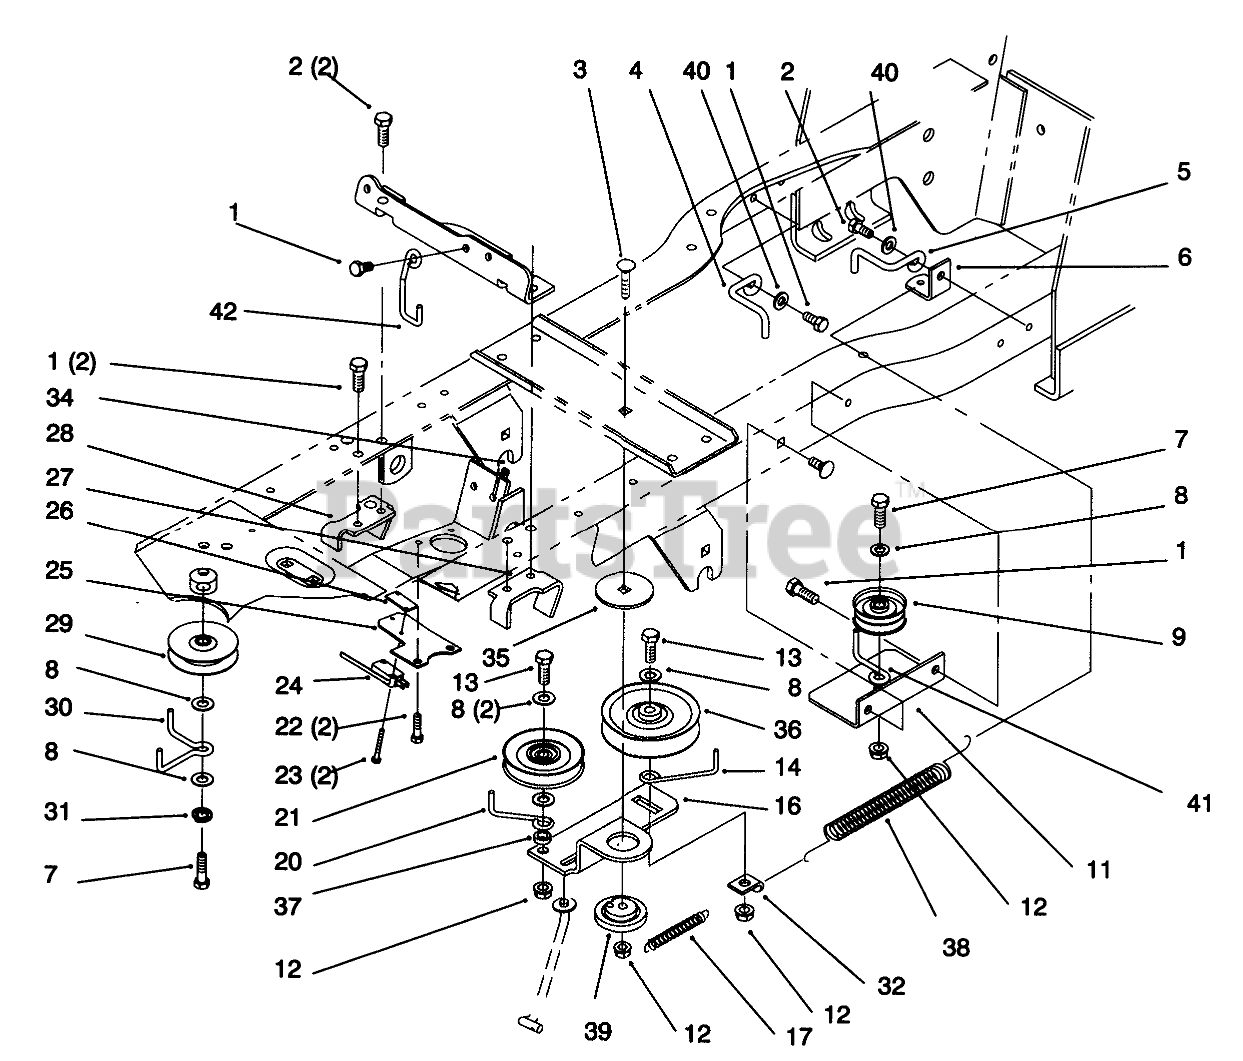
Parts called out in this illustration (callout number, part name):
1	Screw-HH (Only On: 72042, 72062)
2	Screw-TAP (Only On: 72042, 72062)
3	Screw-CARR (Only On: 72042, 72062)
4	Guide-Belt RH (Only On: 72042, 72062)
5	Guide-Belt LH (Only On: 72042, 72062)
6	Bracket-Idler Spring (Only On: 72042, 72062)
7	Screw-HH (Only On: 72042, 72062)
8	Washer-Flat (Only On: 72042, 72062)
9	Pulley-Idler (Only On: 72042, 72062)
11	Bracket-Idler Rear (Only On: 72042, 72062)
12	Nut-Lock (Only On: 72042, 72062)
13	Screw-HH (Only On: 72042, 72062)
14	Guide-Belt (Only On: 72042, 72062)
16	Arm-Idler (Only On: 72042, 72062)
17	Spring-Extension (Only On: 72042, 72062)
20	Guide-Belt (Only On: 72042, 72062)
21	Pulley-Idler (Only On: 72042, 72062)
22	Screw-TAP (Only On: 72042, 72062)
23	Screw (Only On: 72042, 72062)
24	Switch-Micro (Only On: 72042, 72062)
25	Bracket-Micro Switch (Only On: 72042, 72062)
26	Nut-Speed (Only On: 72042, 72062)
27	Bracket-Clutch (Only On: 72042, 72062)
28	Bracket-Brake (Only On: 72042, 72062)
29	Pulley-Idler (Only On: 72042, 72062)
30	Guide-Belt (Only On: 72042, 72062)
31	Washer-Lock (Only On: 72042, 72062)
32	Clip-Spring (Only On: 72042, 72062)
34	Tie Strap (Only On: 72042, 72062)
35	Washer-Bearing (Only On: 72042, 72062)
36	Pulley-Flat (Only On: 72042, 72062)
37	Spacer (Only On: 72042, 72062)
38	Spring-Extension (Only On: 72042, 72062)
39	Bushing (Only On: 72042, 72062)
40	Washer-Flat (Only On: 72042, 72062)
41	GUIDE-BELT
42	GUIDE-BELT
